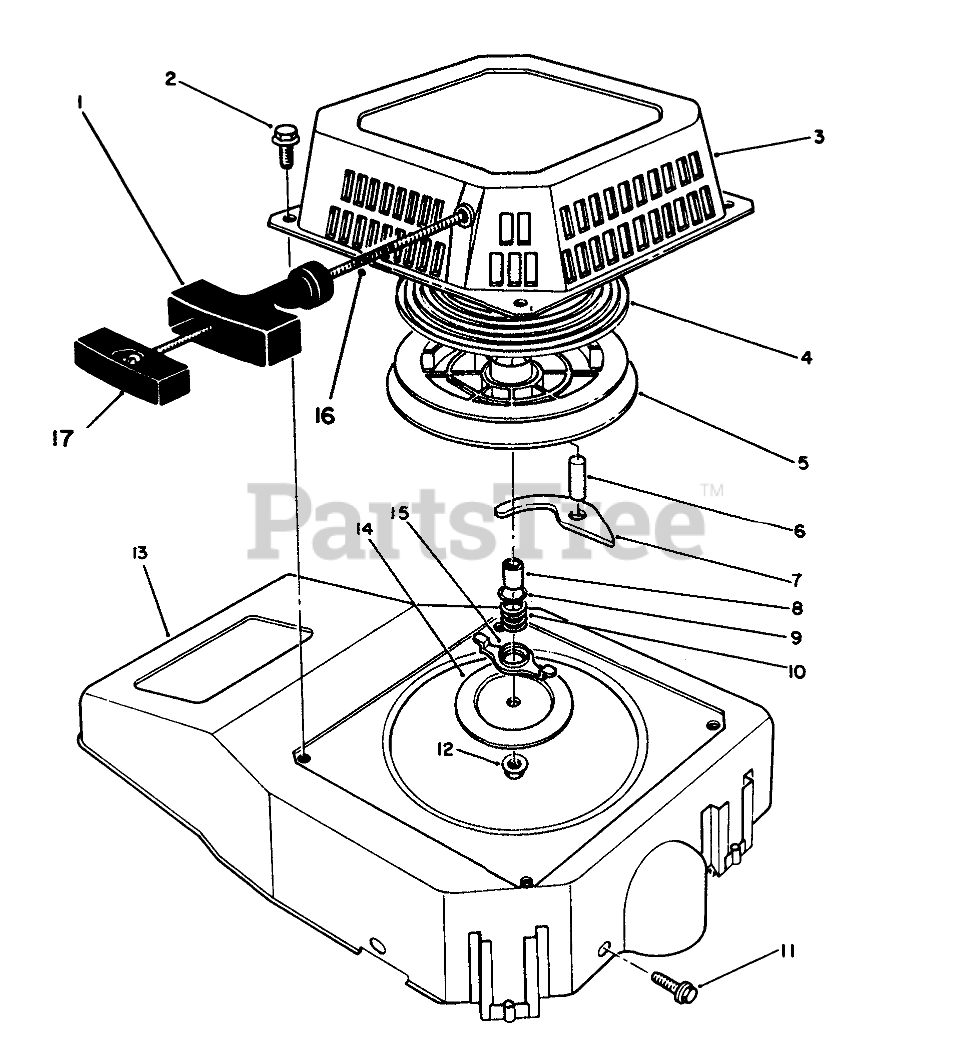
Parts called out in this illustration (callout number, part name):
1	HANDLE
2	SCREW-HHF
3	Case-Recoil
4	SPRING
8	Spacer
9	WASHER
10	Spring-Friction
13	SHROUD
14	PLATE
15	Guide-Paw
16	ROPE-STARTER
17	RETAINER HANDLE
